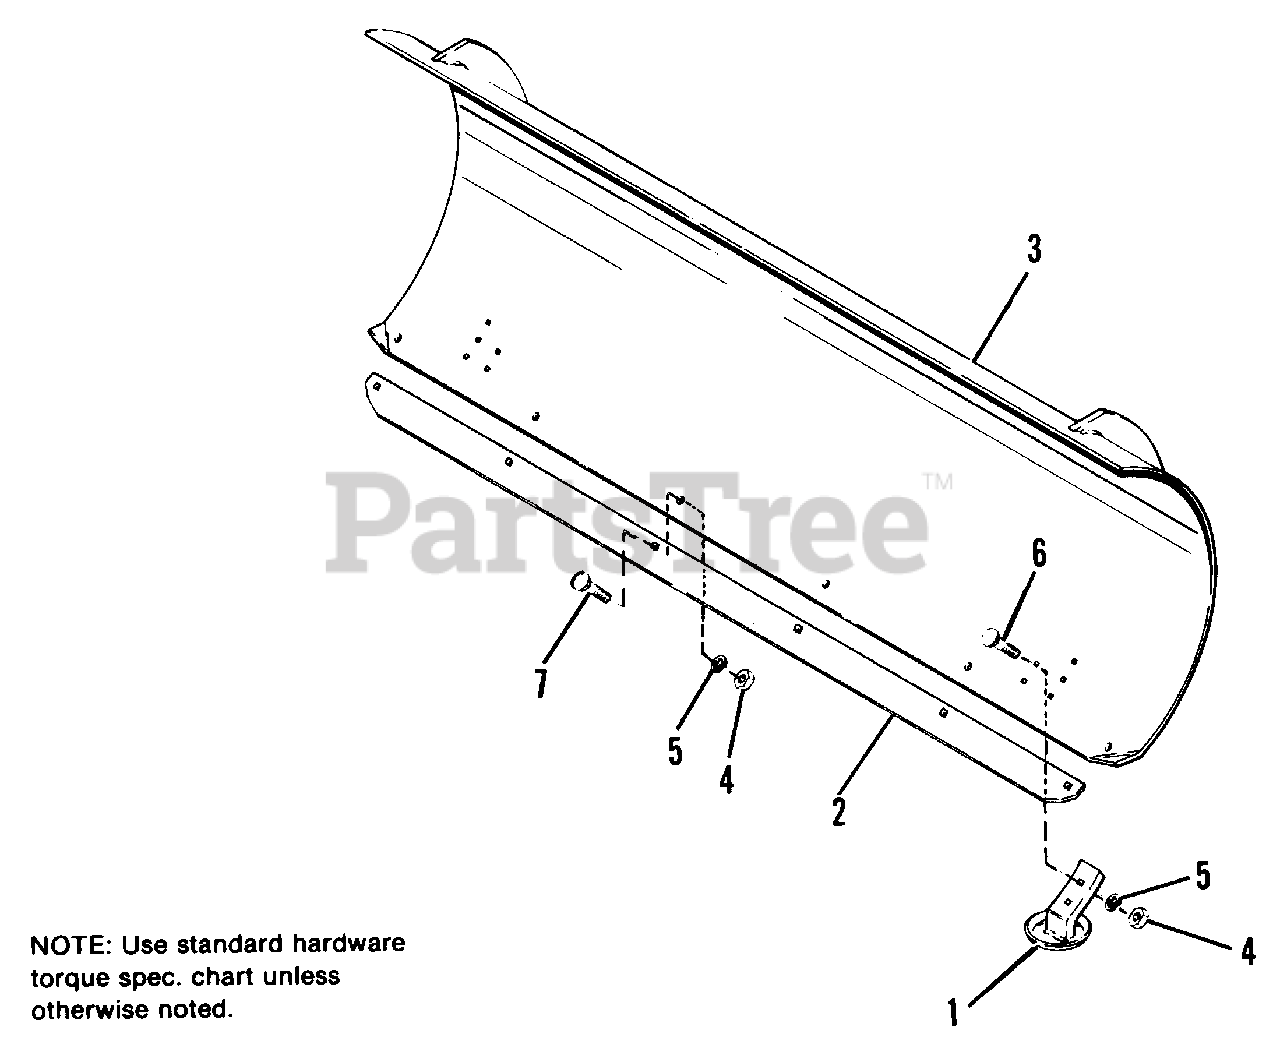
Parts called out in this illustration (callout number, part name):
2	PLATE, Wear
3	BLADE ASSY.
4	NUT, Hex, Full, 3/8-16
5	LOCKWASHER, 3/8
6	CARRIAGE BOLT, 3/8-16 x 1
7	CARRIAGE BOLT, 3/8-16 x 3/4
